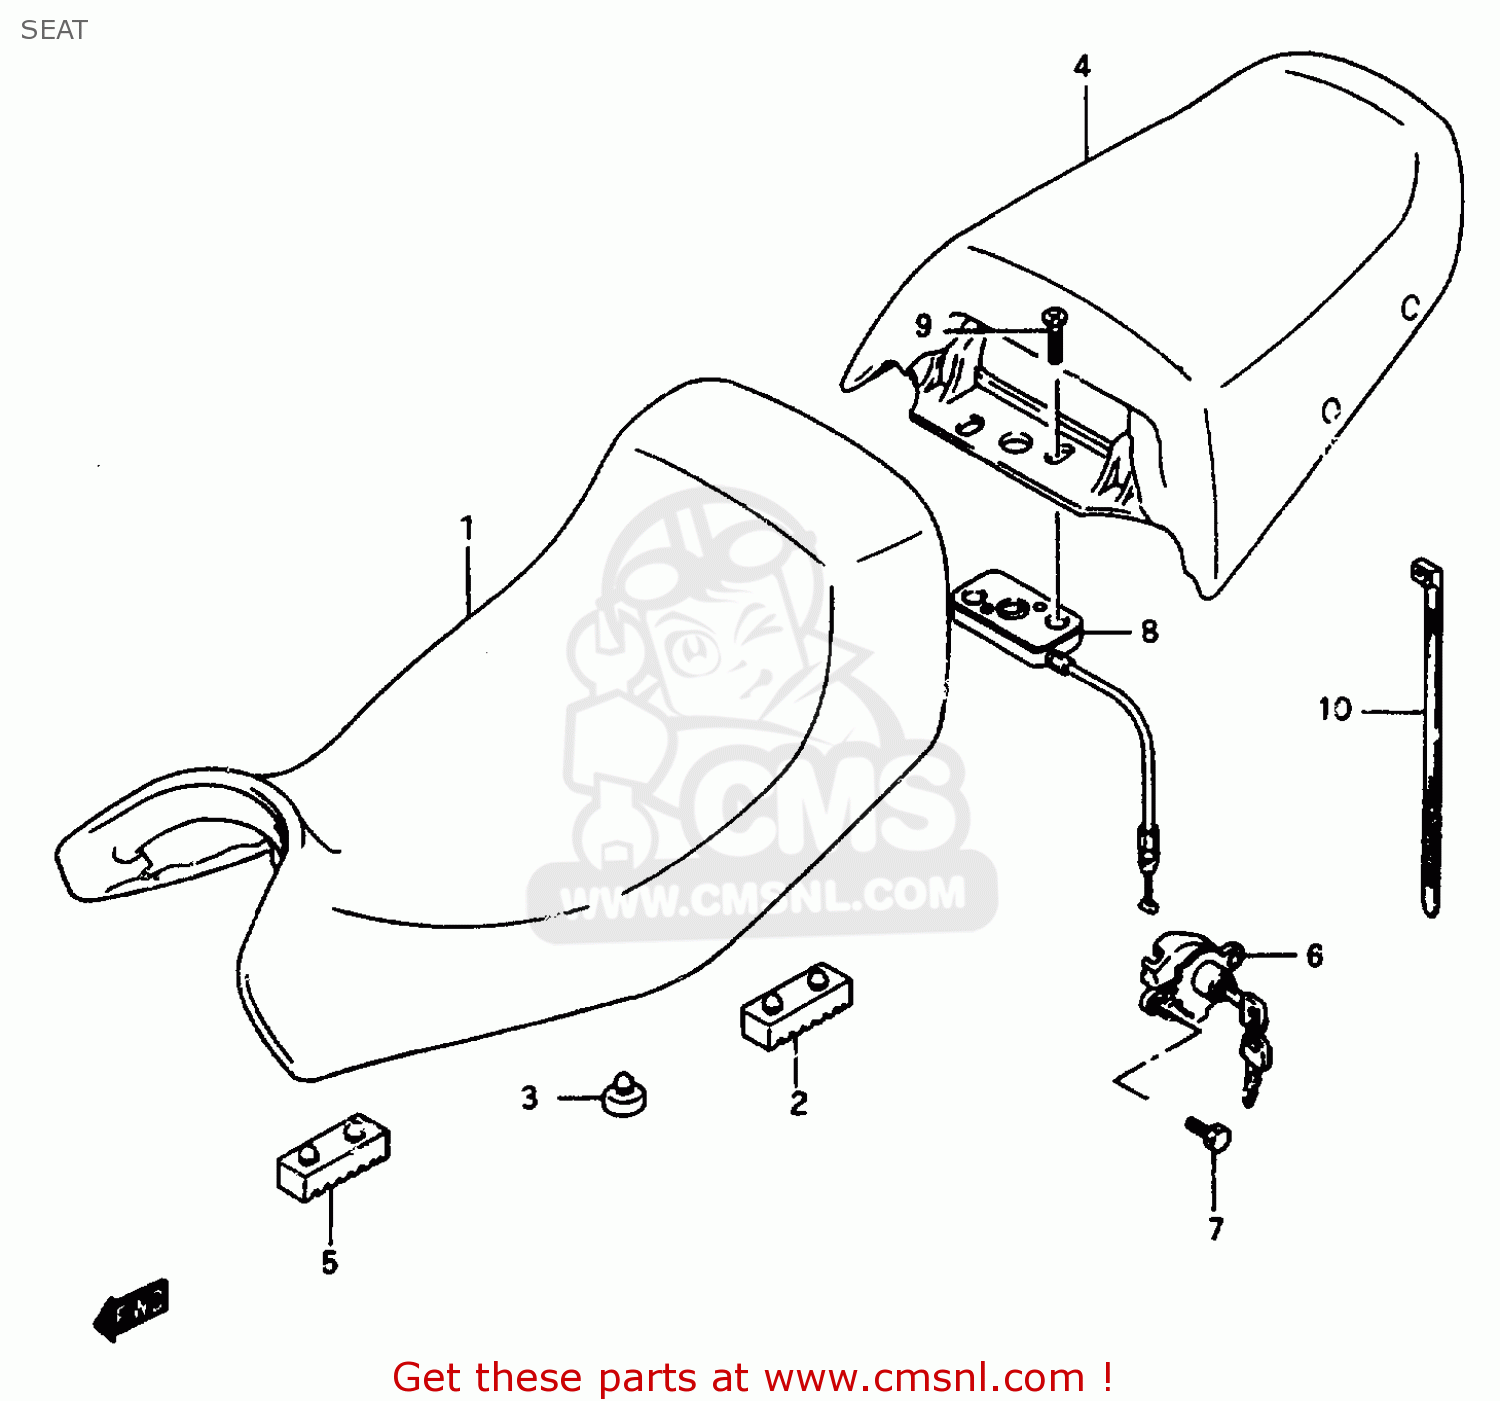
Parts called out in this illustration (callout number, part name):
1	SEAT SET
2	CUSHION,SEAT
3	CUSHION
4	SEAT SET,PILLION
5	CUSHION,SEAT(40X20X15)
6	LOCK SET,SEAT
7	BOLT
8	BRACKET,SEAT SUPPORT RR
9	SCREW
10	CLAMP L:165
